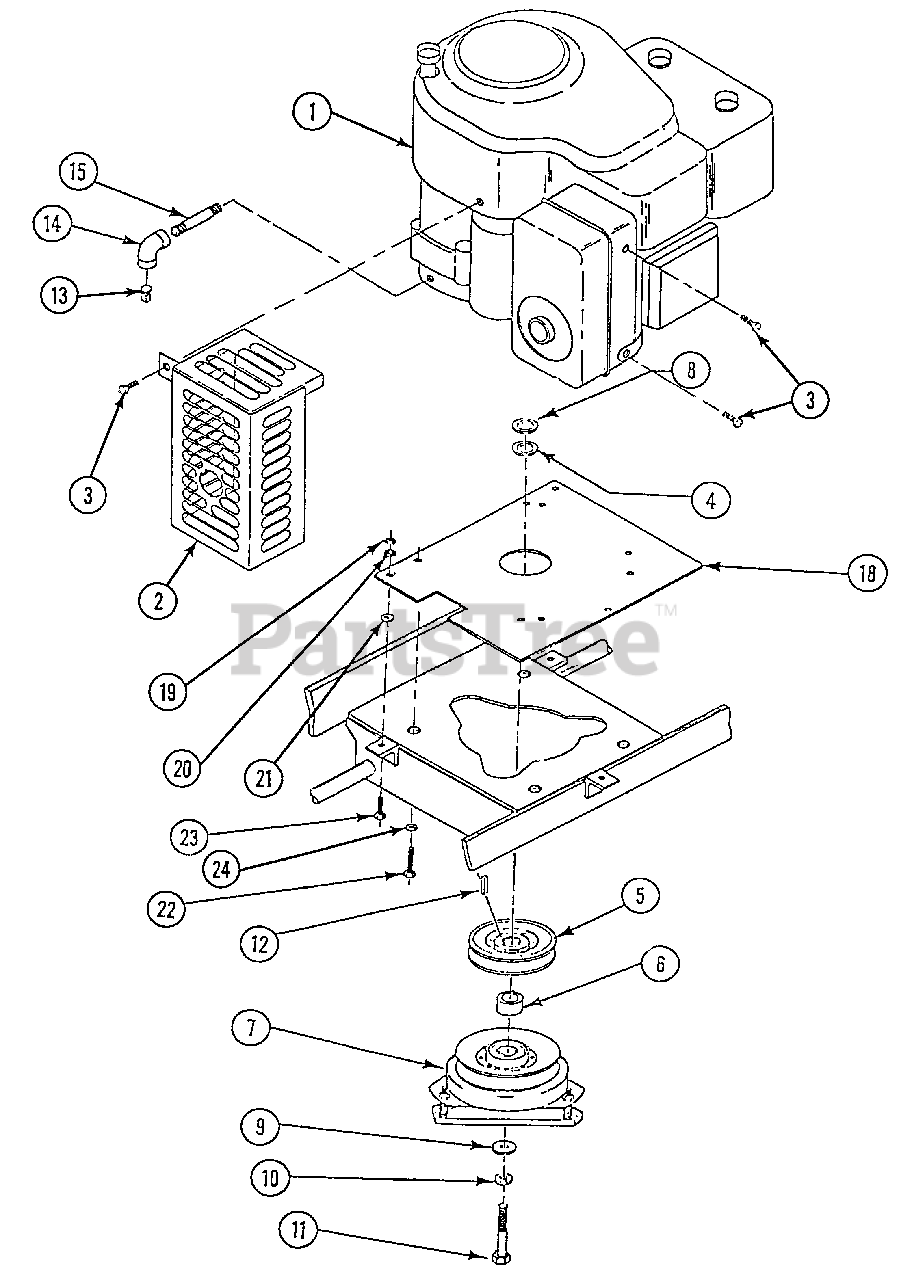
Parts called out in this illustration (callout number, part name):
1	* ENGINE, 12.5 HP B&S VAN GUARD Mod. 404707-0019-01
2	MUFFLER GUARD WLDT.
3	CAPSCREW, M6 X 1 X 12
4	WASHER, 1" 10 GA.
5	PULLEY, BK 52-1
6	SPACER PULLEY/ELECTRIC CLUTCH
7	CLUTCH, ELECTRIC #5210-17
8	WASHER, 1" SPECIAL
9	WASHER, 15/32" I.D.
10	LOCKWASHER, 7/16 SPLIT SPRING
11	CAPSCREW, 7/16-12 X 3" GR.5
12	SQUARE KEY, 1/4 X 1"
13	3/8 PIPE PLUG, BLACK
14	ELBOW, 3/8 90 DEGREE, SCH. 40
15	NIPPLE, 3/8 X 3" SCH. 401 BLACK
18	MOTOR MOUNTING PLATE
19	NUT, 5/16-24 UNF, GR.5
20	LOCKWASHER, 5/16 HEAVY SPRING
21	WASHER, 5/16 STD. FLAT
22	CAPSCREW, 3/8-16 X 1" GR.5
23	CAPSCREW, 5/16-24 X 1" GR.5
24	LOCKWASHER, 3/8 SPLIT SPRING
